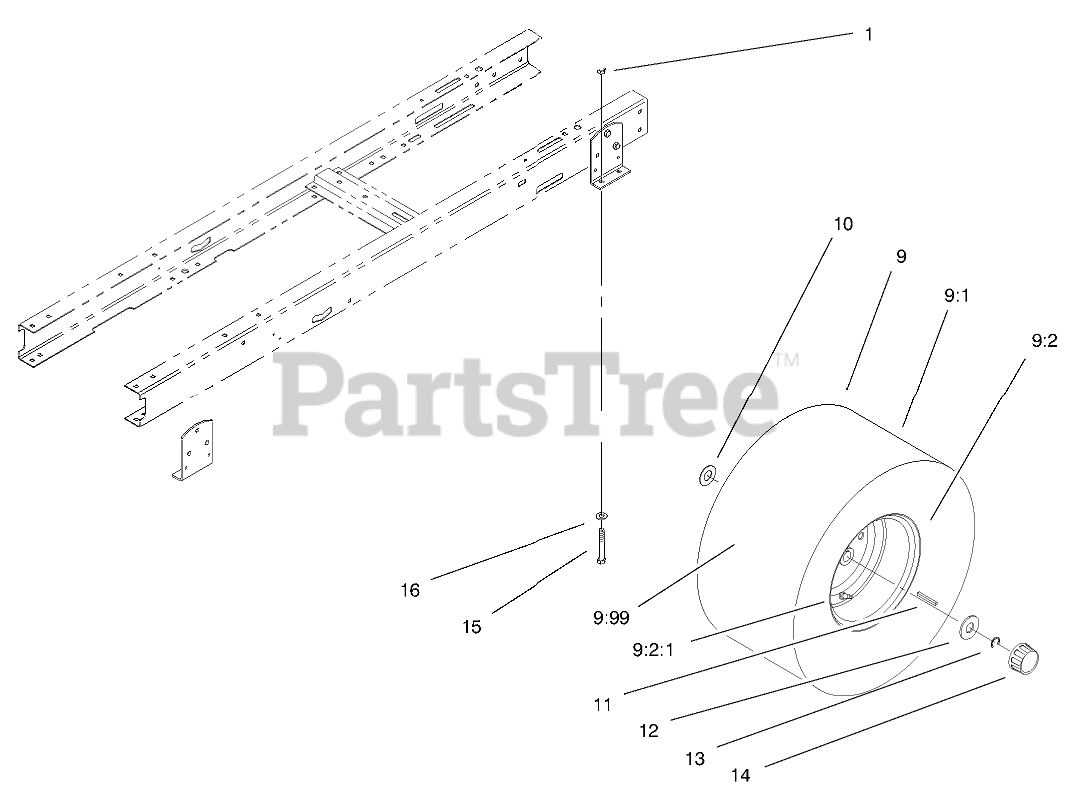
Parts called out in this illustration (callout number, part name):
1	NUT-LOCK, NI
9	Wheel & tire ASM,Rear
9:1	TIRE
9:2:1	STEM-VALVE
9:99	Tube
10	WASHER-THRUST
11	KEY-SQUARE
12	WASHER-PLAIN
13	E-RING
14	CAP-HUB
15	SCREW-HH
16	WASHER-PLAIN
